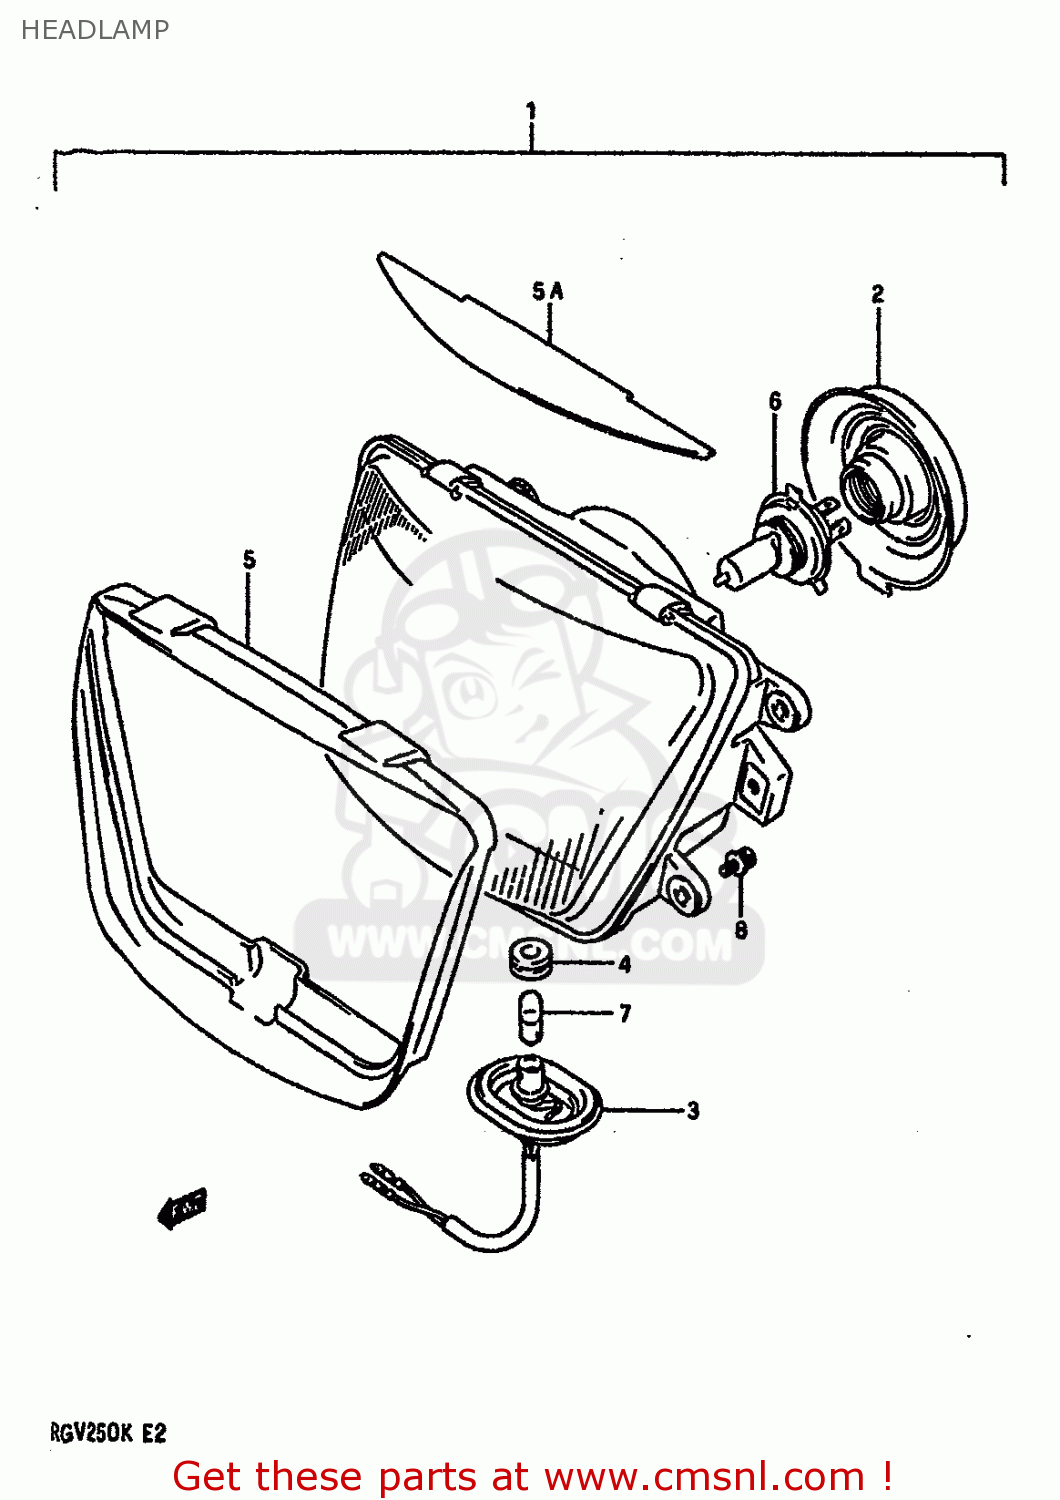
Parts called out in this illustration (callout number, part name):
1	HEADLAMP ASSY
2	COVER,SOCKET
3	SOCKET
4	JOINT,RUBBER
5	SHEAD,HEADLAMP
5A	CUSHION
6	BULB(12V60/55W,H4)
7	BULB
8	SCREW
